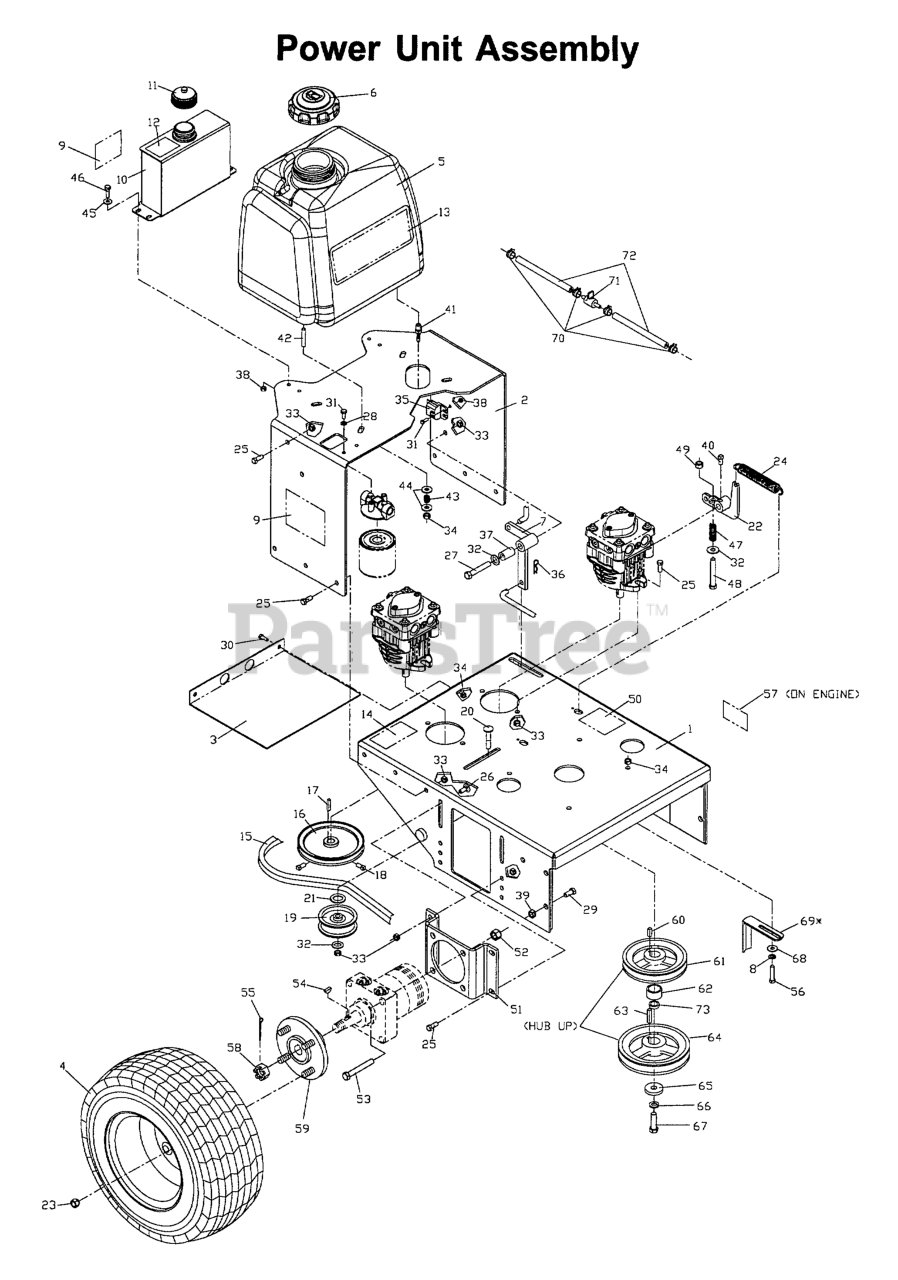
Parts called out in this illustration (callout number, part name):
1	REAR DECK W/DECALS
2	TANK SUPPORT
3	LOWER BELT SHIELD
4	WHEEL, COMPLETE
6	FUEL CAP ANTI-SPLASH
7	BELL CRANK
8	WASHER.LOCK.HVY.HLCL.SPR.5/16
9	DECAL, CROWN H
10	OIL TANK BLK
11	HYDRAULIC CAP
12	DECAL, MOBIL 1
13	DECAL, WH4817
14	DECAL, BELT DRIVE
15	TRANSMISSION BELT
17	KEY 5 MM SQ X 25 MM
18	SCREW 5/16C X 5/8 SQ HEAD
19	IDLER PULLEY
20	RHSNB 3/8C X 2
21	WASHER 1/2 FLAT
22	PUMP ARM WELDMENT
23	LUG NUT 1/2F
24	SPRING-TRANS
25	HCS 3/8-16X1.GRD.5.ZD
26	RHSNB 3/8C X 1
27	HCS 3/8C X 2
28	LOCKWASHER 1/4"
29	HCS 7/16-14 X 1 GR 5 ZD
30	HCS 5/16C X 3/4
31	HCS 1/4C X 5/8
32	WASHER 3/8 FLAT
33	NUT 3/8C CENTERBLOCK
34	NUT 5/16C CENTERLOCK
36	HAIRPIN #2
37	BUSHING, SLEEVE
38	NUT 1/4C CENTER LOCK
39	NUT 7/16C CENTERLOCK
40	5/16C X 5/8 "V" POINT
41	HOSE BARB 90 DEGREE
42	STUD, 5/16C
44	WASHER 5/16 FLAT
45	WASHER 1/4 FLAT
46	HCS 1/4C X 3/4 HCS
48	HEX SCREW 3/8-20 X 2.75
49	NUT 3/8-16 NYLOC
50	DECAL, PROP. 65
51	MOTOR MOUNT, 48
52	NUT 1/2-13 HEX NYLOC ZD
53	HCS 1/2C X 2 3/4
54	KEY, #808 WOODRUFF
55	COTTER PIN
56	HCS 5/16C X 1 3/4
57	DECAL, EXHAUST
58	NUT 3/4-16 HEX SLTD GR5 ZD
59	HUB.WHEEL.ZTR
60	KEY 1/4 SQ X 3/4
63	KEY 1/4 SQ X 1 1/8
64	PULLEY, ENGINE
65	SPINDLE WASHER
66	WASHER 7/16 LOCK
67	HCS 7/16F X 1 1/2
68	WASHER 5/16 FLAT
69	BELT GUIDE
70	HOSE CLAMP
71	FUEL VALVE
72	GAS LINE 10"
73	BUSHING, 10GA MACHINERY
539103462	BELT GUIDE - LONG
539104628	WHEEL
539912234	VALVE STEM TR-412
